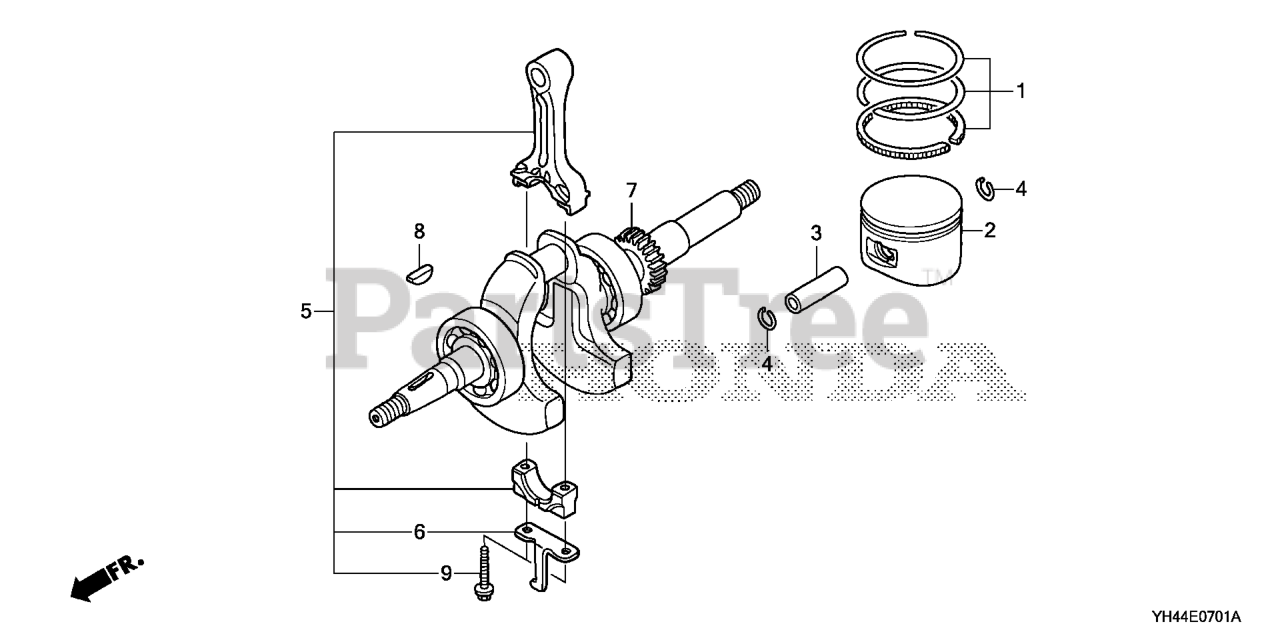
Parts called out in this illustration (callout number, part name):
1	RING SET, PISTON (STD)
2	PISTON (STD)
3	PIN, PISTON (10X33)
3	PIN, PISTON
4	CLIP, PISTON PIN (10MM)
5	ROD ASSY., CONNECTING
6	DIPPER, CONNECTING ROD
7	CRANKSHAFT
8	KEY, SPECIAL
9	BOLT, CONNECTING ROD
